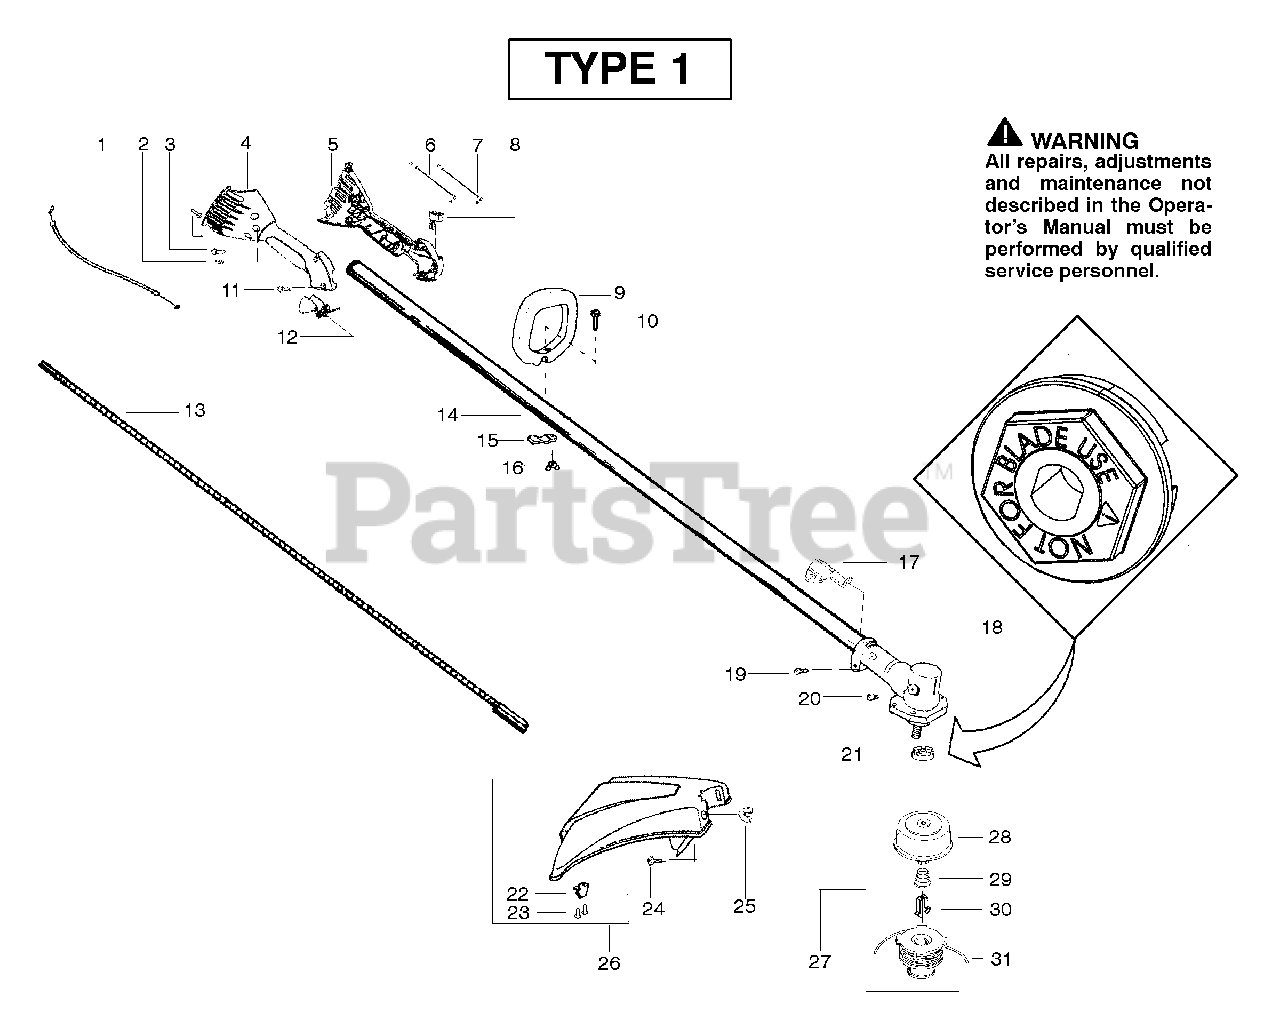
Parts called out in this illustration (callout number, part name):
1	Assy-Throttle cable
2	Screw-alignment
4	Throttle Hsg.-Right
5	Kit-Left Throttle Hsg.
6	Assy-Front wire
7	Assy- Front Wire (upper)
8	Kit-Switch
9	Assy-Handle
12	Trigger-Throttle
13	Shaft-Flex
14	Assy-Driveshaft
15	Clamp-Assist Handle
16	Wingnut
17	Bracket-Shield
18	Assy.-Gearbox non blade
21	Non-Blade Dust cup
22	Limiter-Line
23	Screw
25	Wingnut
26	Kit-Shield Ass'y.
27	Accy.- Cutting Head
28	Assy.-Hub/Arbor (3/8lh, 2x)
29	Spring-Return
30	Retainer-Spool
31	Accy.-Wound Spool
